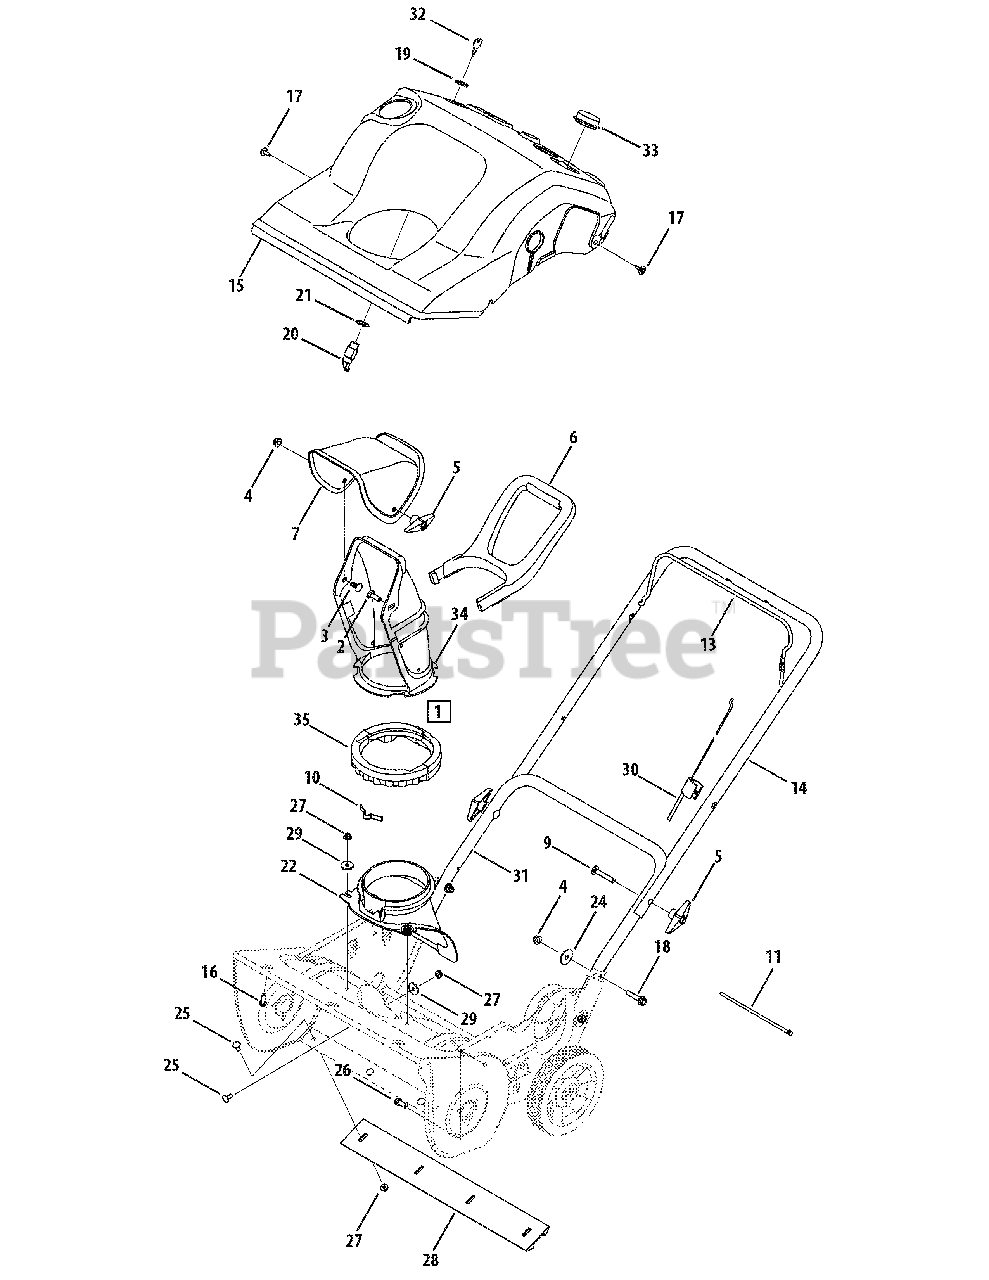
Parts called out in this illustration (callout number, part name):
1	Chute Assembly
2	Carriage Bolt 5/16-18 x 1.0"
3	Carriage Bolt 5/16-18 x 0.750"
4	Flange Lock Nut, 5/16-18
5	Wing Knob, 5/16-18
6	Chute Handle
7	Upper Chute
8	Lock Washer, 5/16
9	Carriage Screw, 5/16-18 x 2.0 Gr. 5
10	Chute Adjustment Spring
11	Cable Tie
12	Screw, 5/16-18 x 1.50
12	Screw, 5/16-18 x .625
15	Shroud Assembly 2 Cyc. 3.5hp.
15	Shroud Assembly 2 Cyc. 4.5hp.
15	Shroud Assembly 2 Cyc. 5.5hp.
16	Screw, 1/4-15 x .50
17	Self-tapping Screw, #10-16 x .625"
18	Hex Flange Screw 5/16-18 x 1.50
19	Hex Nut 5/8-32 x .12 Special
20	Key Switch-Electric Start
21	Lock Washer Internal .625 x 1.058
22	Chute, Adapter 5" Dia
23	Spcr., .325 ID x .625 OD x .88 Lg.
24	Flat Washer .330 x 1.25 x .06
25	Screw, 1/4-20 x .62
26	Truss Machine Screw, 5/16-18 x .75
27	Hex Flange Lock Nut, 1/4-20
28	Shave Plate,19.88
29	Flat Washer .265 x .938 x .120
30	Control Cable
32	Ignition Key
33	Spark Plug Cover
34	Lower Chute 5" Dia
35	Ring-Lower Chute
